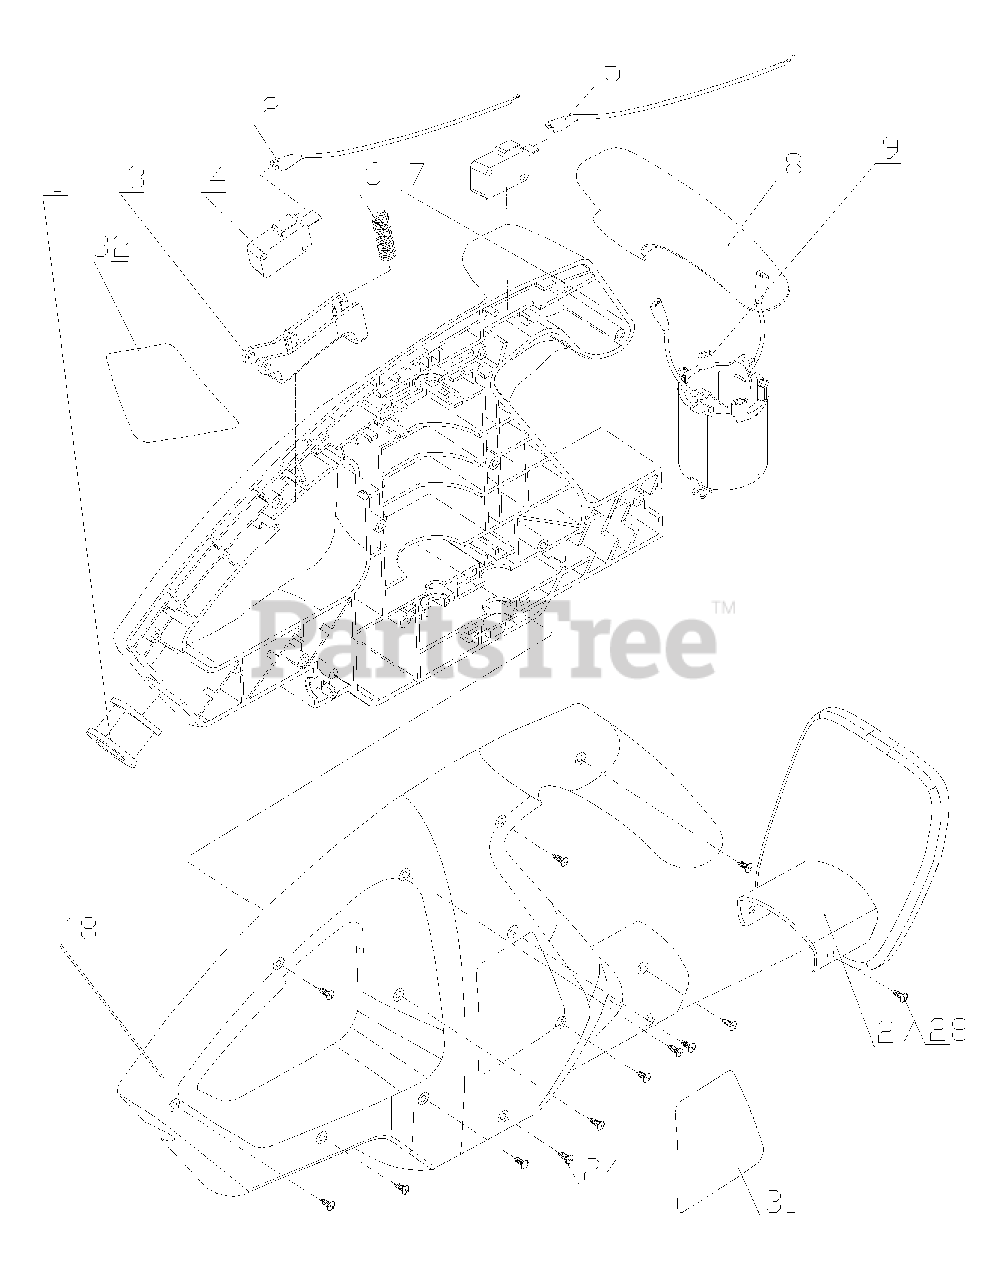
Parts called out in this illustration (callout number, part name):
7	HOUSING (L)
9	FIELD ASS'Y
12	16" BLADE
14	ECCENTRIC SHAFT
15	OUTPUT SHAFT
17	BRUSH HOLDER
18	HOUSING (R)
19	TERMINAL BLOCK
21	STRAIN RELIEF
22	CORD GUARD
23	POWER CORD
25	BLADE COVER
31	LABEL (R)
32	LABEL (L)
